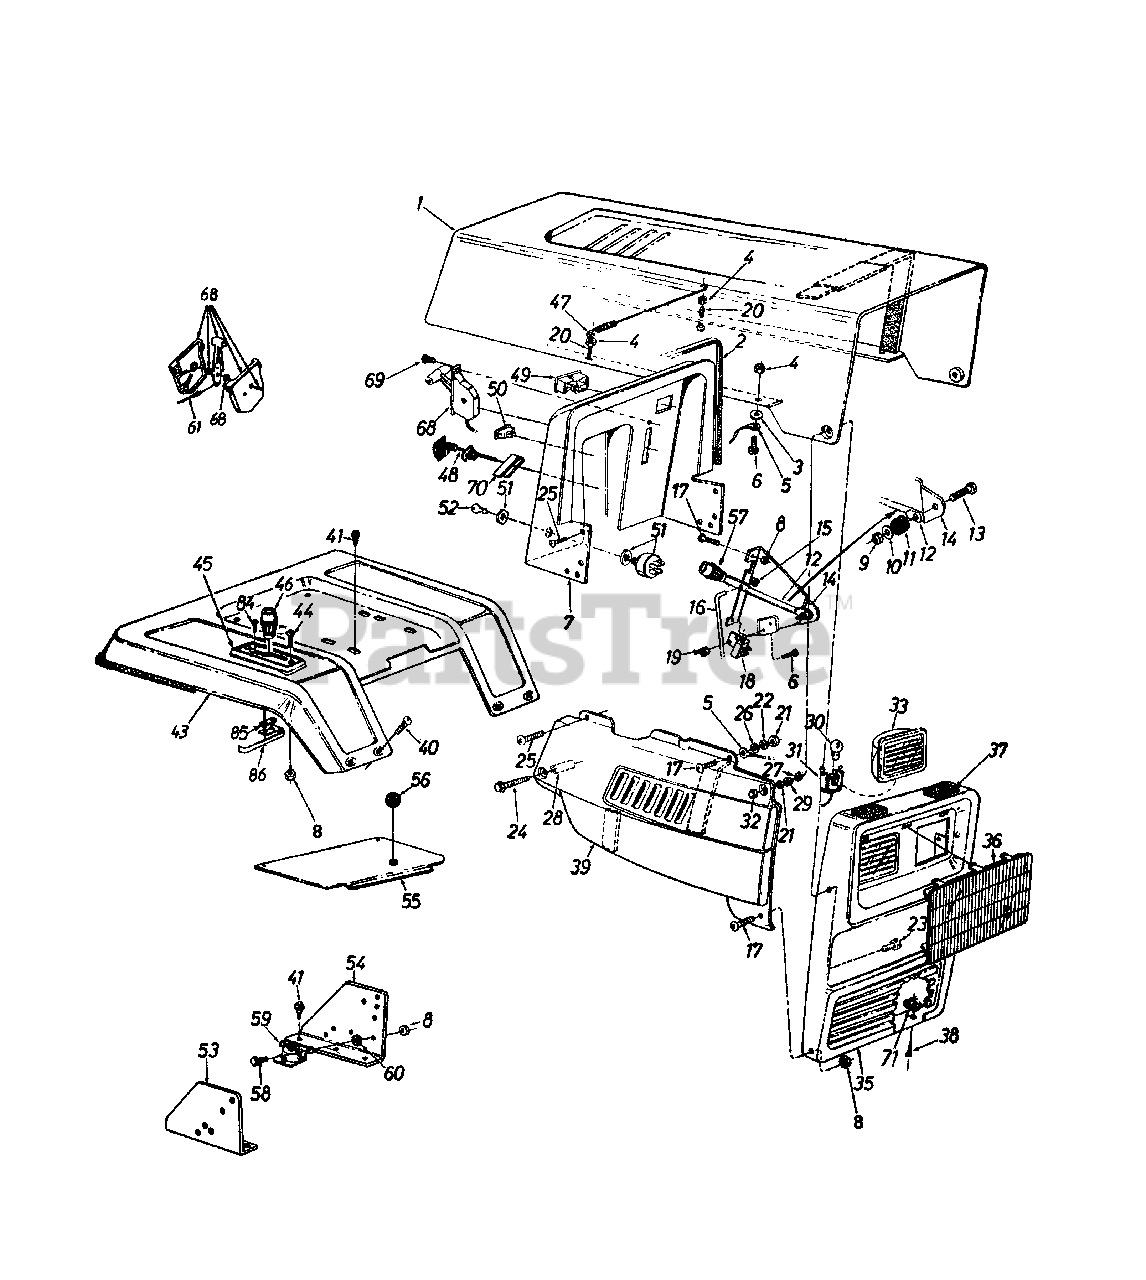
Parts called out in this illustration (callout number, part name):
3	Fl-Wash. .188" I.D. x .43" O.D.
4	Hex Sems Nut #10-24 Thd.
5	Hood Stop
6	Truss Mach. Scr. #10-24 x .5" Lg.
9	Hex L-Nut 1/4-20 Thd.
10	Fl-Wash. .281" I.D. x .73" O.D.
11	Rubber Washer
12	PTO Lever
13	Hex Bolt 1/4-20 x 1.25" Lg.
16	Deck Control Rod
17	Truss Mach. Scr. 1/4-20 x .5" Lg.
18	Safety Switch
19	Hex Sems Nut #10-24 Thd.
20	Hex Bolt 10-24 x 1.0" Lg.
21	Hex Nut 1/4-20 Thd.
22	L-Wash. 1/4" I.D.
23	Hex Bolt 1/4-20 x .88" Lg.
24	Hex Wash. TT-Tap Scr. 1/4-20 x 1.75" Lg.
25	Hex TT-Tap Scr. 1/4-20 x .75" Lg.
26	Fl-Wash. .25" I.D. x .62"
27	Spr. Wash. .39" I.D. x .62"
28	Spacer .26" I.D. x .375"
29	Shld. Spacer .375" Dia. x .125" Lg.
30	Lamp
31	Socket
32	Acorn Nut 1/4-20Thd.
33	Headlight Housing
37	Foam Strip
38	Hex Bolt 5/16-18 x .75" Lg.
41	Hex Wash. AB-Tap Scr. 5/16 x .75" Lg.
45	Speed Selector Plate
46	Shift Knob
47	Hood Spring
48	Choke Control 46" Lg.
49	Ammeter
50	Light Switch
51	Ignition Switch
52	Ignition Key
57	Knob-Blade Clutch
58	Hex Bolt 1/4-20 x .5" Lg.
59	Solenoid
60	Ext. L-Wash. 1/4" I.D.
61	Throttle Wire 35" Lg.
68	Throttle Control Box Assy.
69	Truss Mach. AB-Tap Scr.
70	Retainer Clip
71	U-Nut 5/16-18 Thd.
84	Hex Wash. Hd. AB-Tap Scr. #8 x .5"
85	Insulator Nut Plate
86	Reverse Safety Switch
16725-0640	PANEL-SIDE RH - CO-OP GREEN (0640)
16725-0665	PANEL-SIDE RH - YARDMAN GREEN (0665)
16725-0691	PANEL-SIDE RH - BLACK JACK (0691)
17309B-0483	PANEL-SIDE-LH - CHARCOAL GRAY (0483)
17309B-0638	PANEL-SIDE-LH - MTD/TROY-BILT RED (0638)
